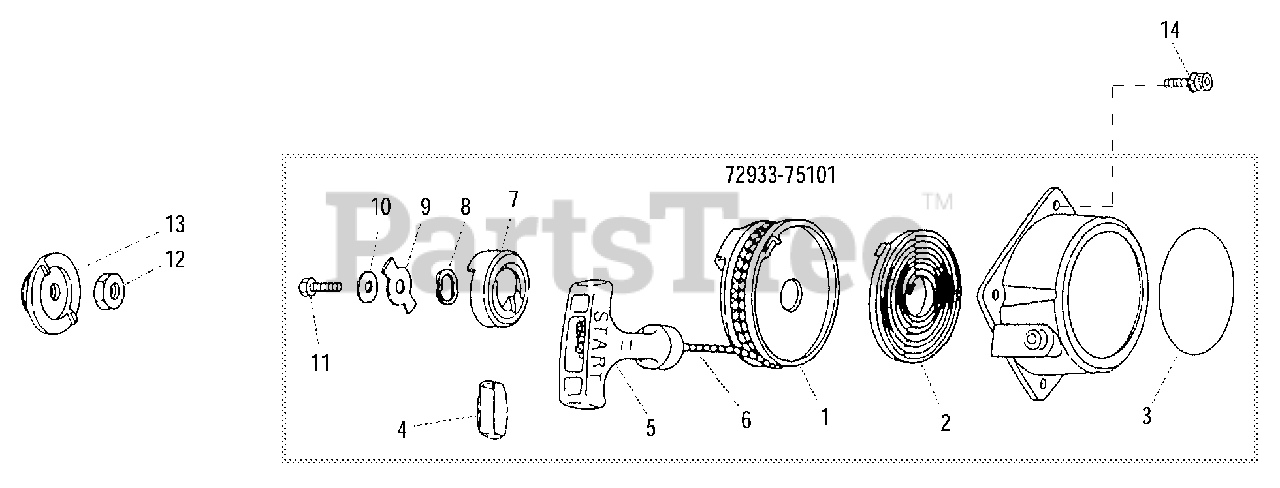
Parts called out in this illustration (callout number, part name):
1	REEL, ROPE
2	SPRING, REWIND
3	LABEL - IDENTIFICATION
4	RETAINER, ROPE
5	HANDLE
6	ROPE, STARTER
7	PAWL, STARTER
8	WASHER - SPRING
9	RETAINER
10	WASHER - 5
11	SCREW - 5
12	NUT - 8
13	PAWL
14	SCREW - 4X12
72933-75101	STARTER ASSY
